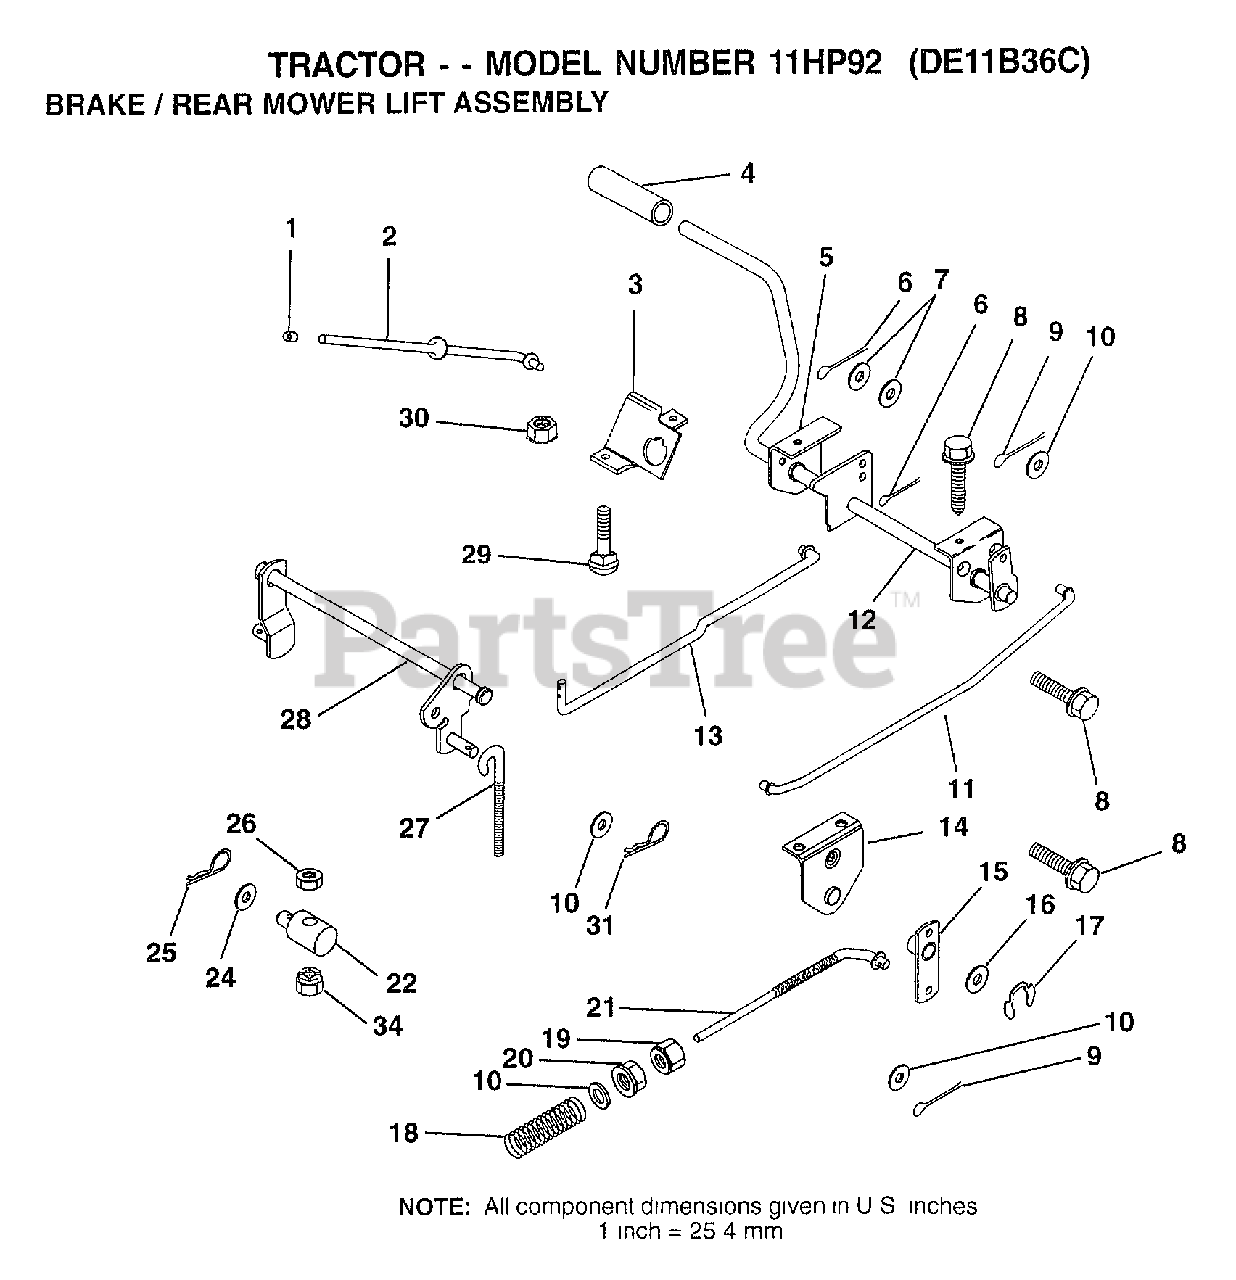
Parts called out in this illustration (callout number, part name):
1	PLUNGER CAP T
2	"ROD,PARK BRAKE"
3	"BRKT,PARK BRAKE"
4	FOOT PEDAL COVER
5	"BRKT,CLU PEDAL LH"
7	WASHER
8	SCREW LT
9	COTTER PIN
10	WASHER
11	"ROD,FRT BRAKE"
12	PEDAL ASM CL/BK36
13	"ROD,CLUTCH"
14	"BRKT,LIFT SHAFT"
15	PVT BRAKE ARM ASM
16	WASHER T
17	KLIP RING
18	SPRING ROD BRAKE
19	NUT
20	NUT
22	TRUNNION.LIFT.
24	WASHER
25	SPRING.RETAINER
26	LOCKNUT
27	"LINK, MOWER REAR"
28	LIFT ASM MOW REAR
31	RETAINER.SPRING
